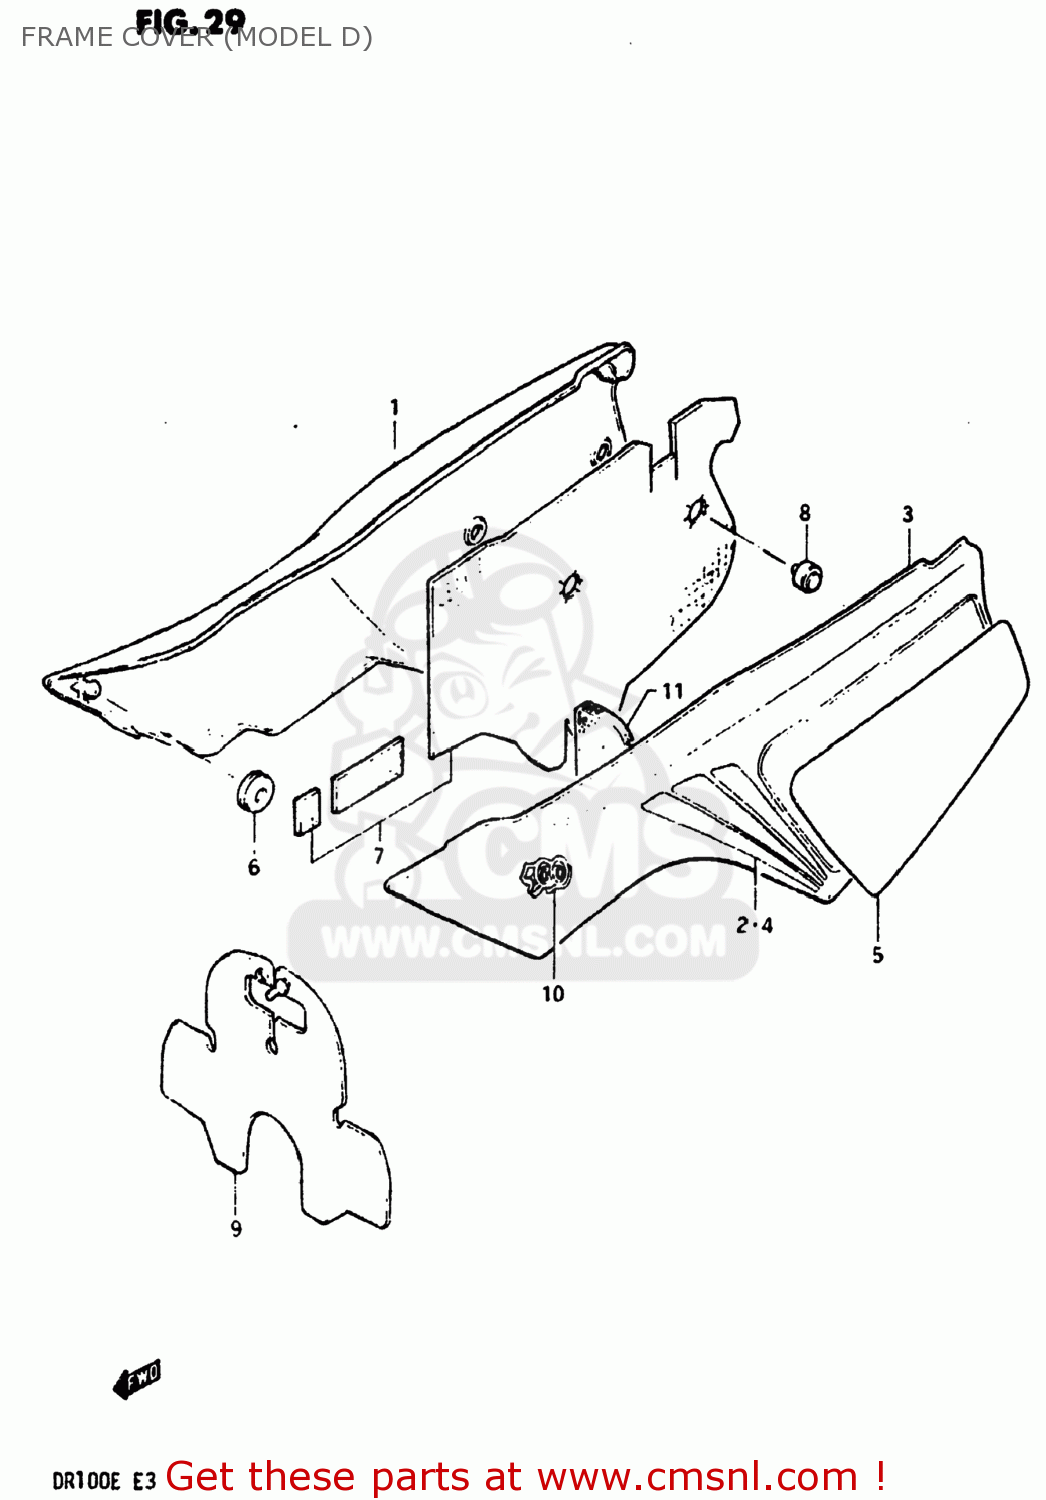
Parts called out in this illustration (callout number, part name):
1	COVER,FRAME,RIGHT
2	TAPE SET,FRAME COVER
3	COVER,FRAME,LEFT
4	TAPE SET,FRAME COVER,LEFT
5	EMBLEM,FRAME COVER
6	CUSHION
7	HEAT SHIELD,FRAME COVER
8	CUSHION
9	MUD FLAP,FRONT
10	EMBLEM
11	MUD GUARD
